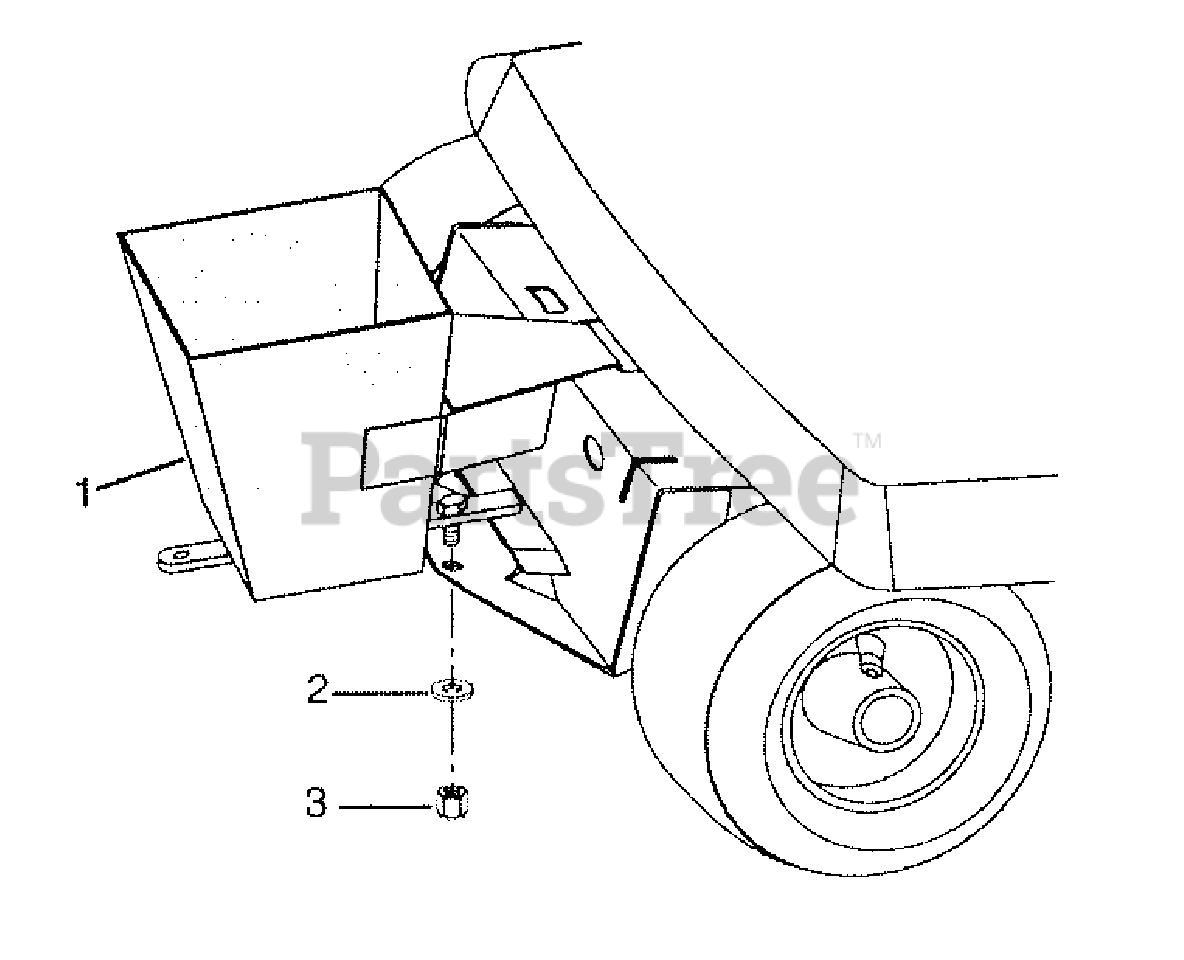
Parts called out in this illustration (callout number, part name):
1	BOX-WEIGHT
2	WSHR-FL-STL.511X1.441X.125 YWZ
3	@NUT-LK-CTR .50-13 YWZC
